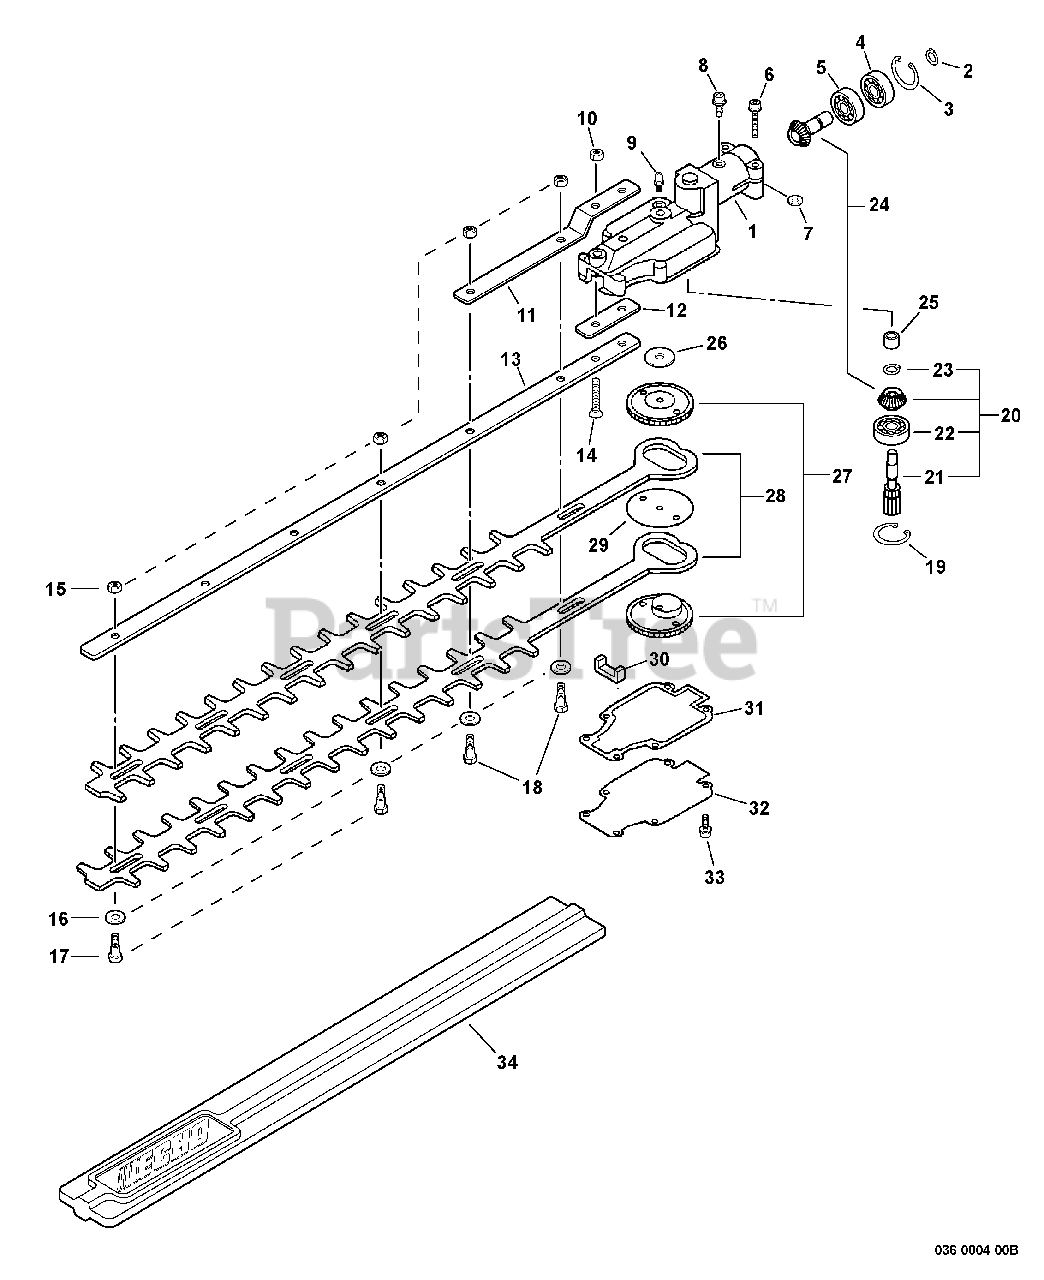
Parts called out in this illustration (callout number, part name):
1	CASE, GEAR - UPPER
2	RING, RETAINING - 12
3	RING, RETAINING - 24
4	BEARING, BALL - 6901Z
5	BEARING, BALL - 6901
6	SCREW - 5X28
8	SCREW - 5X12
9	FITTING, GREASE
10	LOCKNUT - 6
11	BRACKET, BLADE
12	PLATE
13	SUPPORT, BLADE
14	SCREW - 6X35
15	LOCKNUT - 6
16	WASHER - 6
17	BOLT - 6
19	RING, RETAINING - 24
20	SPUR GEAR ASSY
21	GEAR - SHAFT
22	BEARING, BALL - 6901
23	RING, RETAINING
24	GEAR SET
25	BEARING, NEEDLE
27	GEAR - SPUR
28	BLADE, TRIMMER
30	SEAL, FELT
31	GASKET, GEAR CASE
32	LID, GEAR CASE
33	SCREW - 4X12
34	COVER, BLADE
